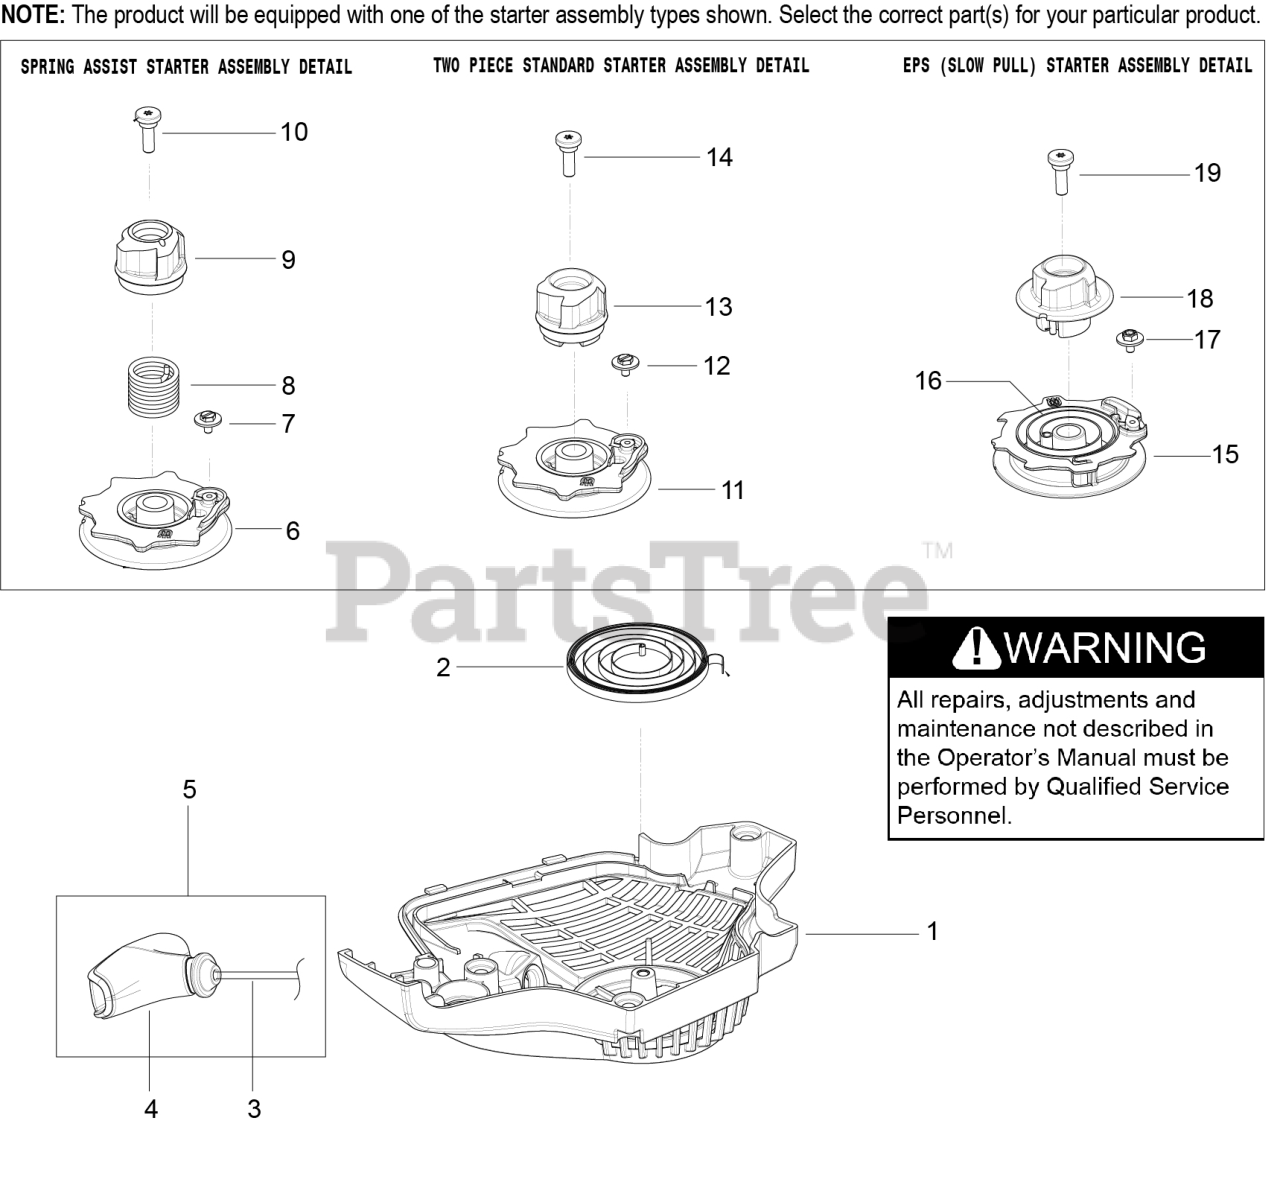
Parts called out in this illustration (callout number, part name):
1	HOUSING FAN PP POULAN GREEN
1	FAN HOUSING
2	SPRING
3	ROPE
4	Handle-Starter
5	ASSY ROPE & HANDLE HUSKY GREY
6	STARTER PULLEY
7	Screw (Incl. in Starter Pulley Kit)
8	Spring-EPS
9	Starter Hub-EPS
10	Screw-Shoulder
11	STARTER PULLEY
12	Screw (Incl. in Starter Pulley Kit)
14	Screw-Shoulder
15	PULLEY STARTER SLOW-PULL
16	SPRING POWER, SLOW-PULL
17	Screw (Incl. in Starter Pulley Kit)
18	HUB ASSY STARTER SLOW PULL
19	Screw-Shoulder
